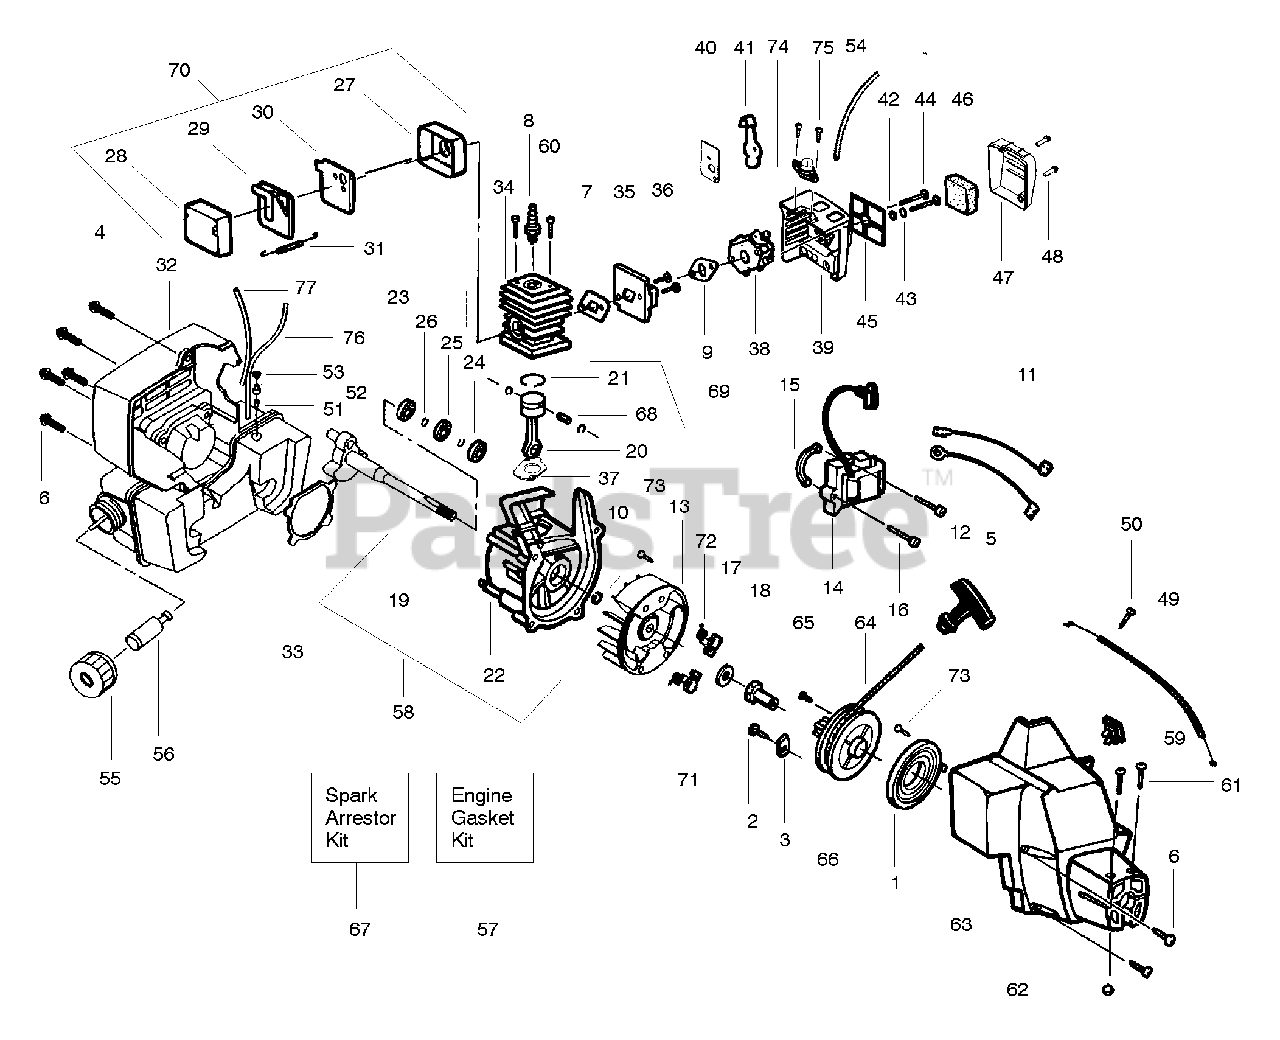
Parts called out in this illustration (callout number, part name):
1	Starter Spring
3	Retainer
5	Starter Handle
6	Screw
7	Cylinder Gasket
8	Spark Plug
10	Retainer
11	Lead Wire
12	Ground Wire
13	Flywheel Ass'y.
14	Ignition Module
18	Drive Coupling
19	Crankshaft Ass'y.
20	Connecting Rod Ass'y.
21	Piston Ring
22	Crankcase Ass'y.
23	Inner Bearing
24	Outer Bearing
25	C'case Seal
26	Retaining Ring
27	Muffler Body
28	Muffler Cover
29	Muffler Baffle-Exit
30	Muffler Baffle-First
31	Muffler Spring
32	Shroud & Tank Assy. Type 1
32	Shroud & Tank Assy. Type 2 & 3
34	Cylinder
35	Carb. Adaptor Kit
38	Carburetor Type 1 (WA-215)
38	Carburetor Type 2 & 3 (WA-218)
39	Air Box Type 1
39	Air Box Type 2 & 3
40	Choke Plate
41	Choke Shutter
42	Wave Washer
43	Choke Spacer
45	Filter Plate
46	Air Filter Foam
47	Air Filter Cover
49	Throttle Cable Ass'y.
51	Check Valve
53	Retainer
54	Fuel Line-Prim./Carb
55	Fuel Cap Ass'y.
56	Fuel Pickup Ass'y.
57	Engine Gasket Kit
58	C'case & C'shaft Assy.
59	On/Off Switch
63	Fan Housing
64	Rope Kit
66	Starter Pulley
67	Spark Arrestor Kit
68	Piston Pin Retainer
69	Piston Kit
70	Muffler Kit
71	Starter Dog
72	Starter Spring
73	Screw-Flywheel
74	Primer Bulb Ass'y. Type 2 & 3
75	Screw-Primer Type 2 & 3
76	Fuel Line-Prim./Tnk.
77	Fuel Line-Carb/Tnk.
